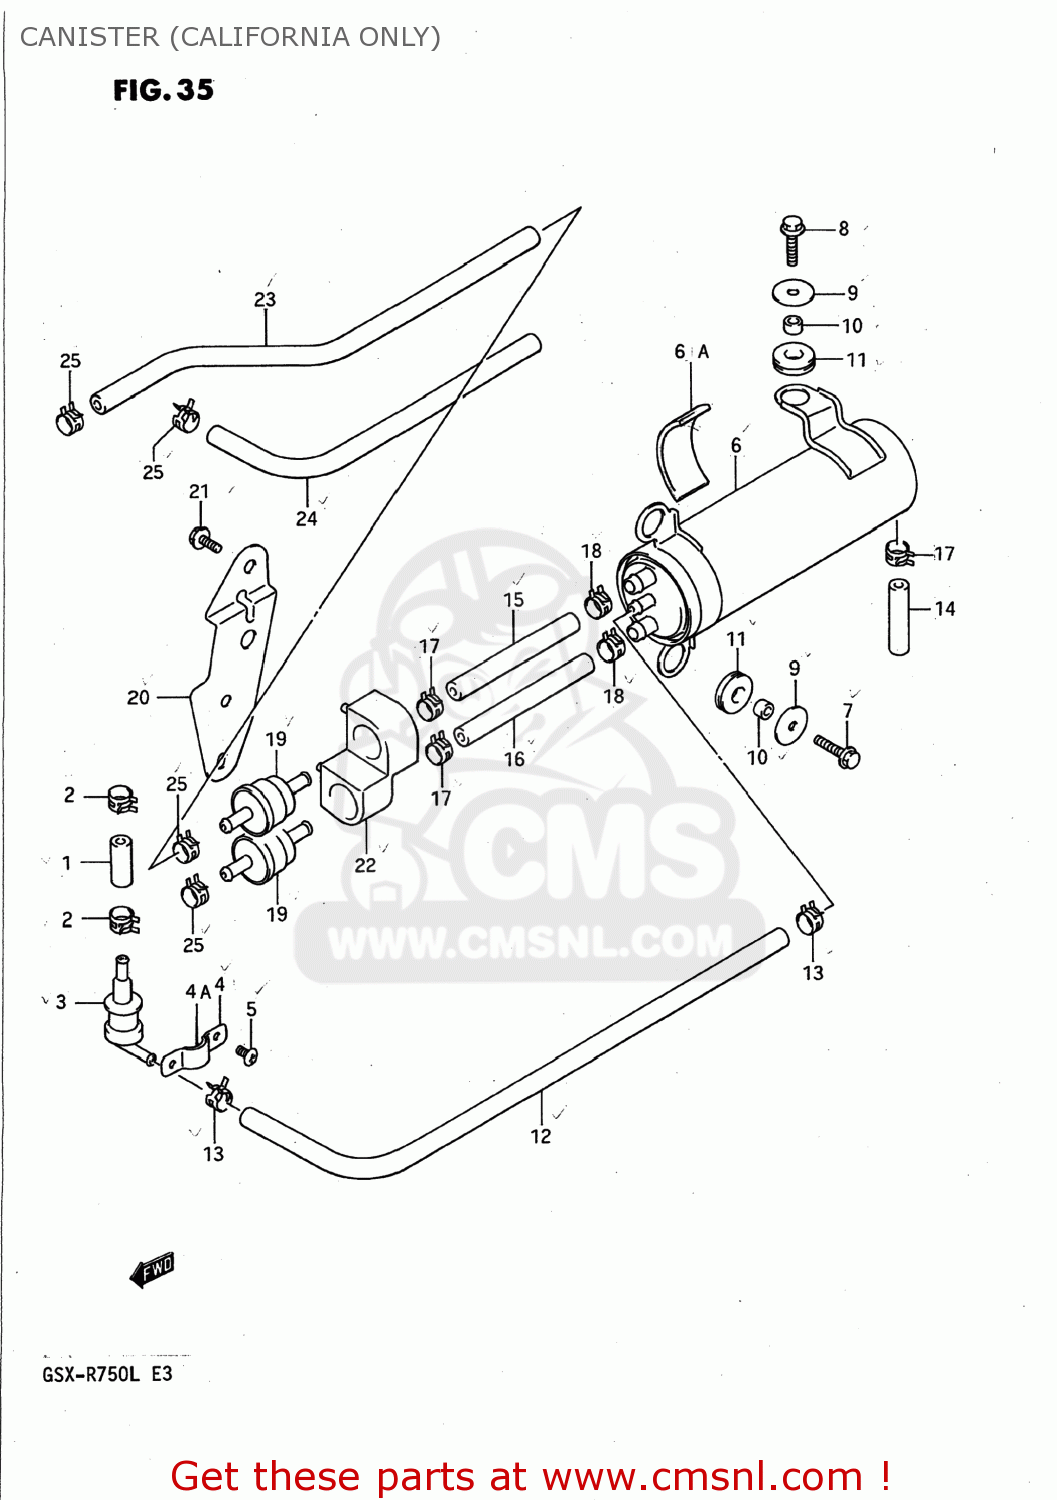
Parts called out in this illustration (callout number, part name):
1	HOSE
2	(CA) CLIP
3	VALVE,FUEL TANK BREATHER
4	PLATE,FUEL TANK BREATHER NO.2
4A	CUSHION
5	SCREW
6	(CA) CANISTER COMP,CHARCOAL
6A	(CA) CUSHION,CANISTER
7	BOLT
8	BOLT
9	WASHER (6.5X24X1.6)
10	SPACER(6.5X10.5X6.5)
11	CUSHION
12	HOSE
13	(CA) CLIP
14	HOSE
15	HOSE
16	HOSE
17	(CA) CLIP
18	CLAMP
19	VALVE,CANISTER PURGE
20	BRACKET,CANISTER
21	BOLT
22	(CA) CUSHION,CANISTER P VA
23	HOSE
24	HOSE
25	(CA) CLIP
